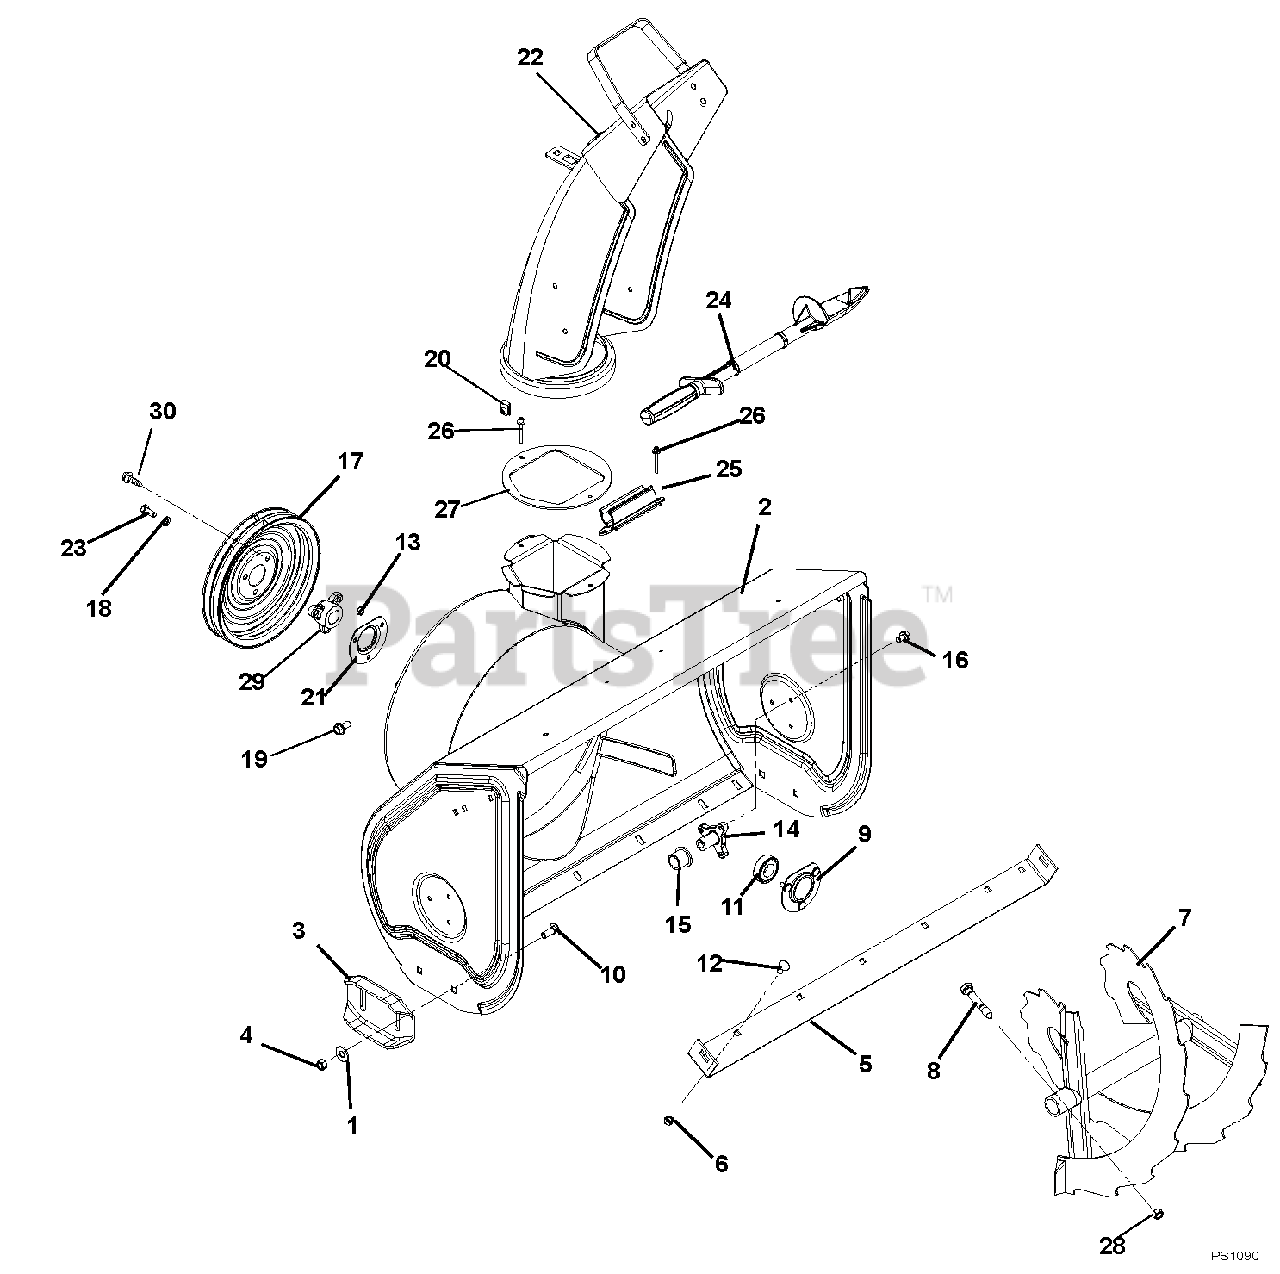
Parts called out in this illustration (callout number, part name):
1	@WSHR-FL-STL.438X1.00X.083 YWZ
2	HOUSING, BLOWER - 27" W/DECAL
3	SKID SHOE, REVERSIBLE - ORANGE
4	@NUT-LK-CTR .38-16 YWZC
5	BLADE, SCRAPER-27"
6	@NUT-LK-TOP-FLG .31-18 YWZC
7	RAKE, LEFT HAND-27" DELUXE
8	SHEAR BOLT SERVICE ASSEMBLY
9	BEARING FLANGE
10	@BLT-RDHDSHSQNK.38-16X1.0 G5YZ
11	BRG-BALL .876 X 1.750 X .50
12	@BLT-RHDSSQNK .31-18X.62 G5YZ
13	@NUT-LK-CTR .25-20 YWZC
14	SUPPORT, RAKE BUSHING
15	BSHG-FLG, NY.778 ID X 1.018 OD
16	SCR-TAP .25-20X.50 HWH TR YWZ
17	PULLEY, SPIN FORM DUAL GROOVE
18	WSHR-LK .312X.097 HVY YWZC
19	SCR-TAP.31-18X.50 HWH TR YWZ
20	NUT-RTNR .375-16X.37
21	BEARING FLANGE
22	CHUTE, DISCHARGE W/CAP & DECAL
23	BLT-HEX .31-24X.75 YWZC GR5
24	DEVICE, SNOW CLEAN OUT
25	MOUNT, SNOW CLEAN OUT
26	RVT-POP .187 YZ
27	BAFFLE, DISCHARGE NECK
28	@NUT-LK-CTR .31-18 YWZC
29	PULLEY HUB, BOLT-ON D-BORE .87
30	@SCR-TAP .31-18X.50 HWH TR YWZ
